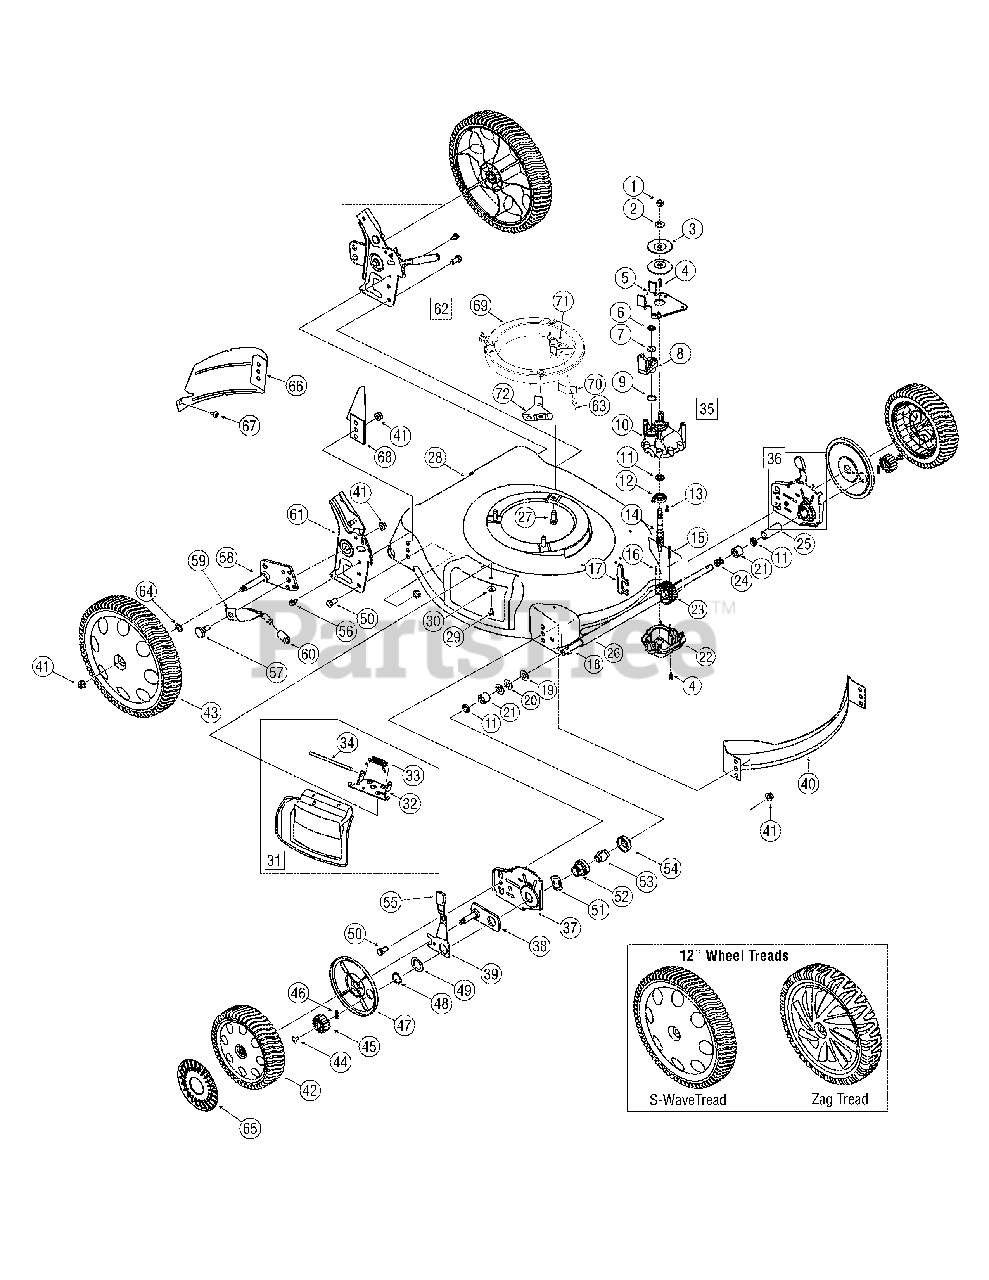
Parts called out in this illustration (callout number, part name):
1	Hex L-Nut 3/8-24
2	Cupped Washer
3	Pulley, 3.82 x .313 x .68
5	Transmission Bracket
6	Push Nut
7	Slotted Washer
10	Upper Housing
11	Oil Seal
14	Pinion Shaft
17	Shifter Fork
19	Flat Washer
21	Plastic Bushing
22	Lower Housing Ass’y
23	28 Tooth Gear
24	Com pression Spring
25	Sleeve Spacer 1.8" Lg.
26	Sleeve Spacer 9.10" Lg.
27	Hex Wash TT Sems Scr 3/8-16 x 1.875
29	Hex Wash S-Tapp Scr 1/4-20 x .50
30	Cupped Washer .265 ID x .75 OD x .062
31	Complete Mulch Plug
32	Chute Hinge
33	Torsion Spring
34	Hinge Pin
35	Transmission Ass’y Com plete
36	RH Height Adjustment Assembly
36	LH Height Adjustment Assembly
37	Height Adjuster Plate - RH
37	Height Adjuster Plate - LH
38	Height Adjuster Pivot Plate Ass'y
39	Spring Lever Front RH
39	Spring Lever Front LH
40	Front Baffle
41	Hex L-FlangeNut 3/8-16 Gr. F, Nylon
42	Wheel Ass'y 8 x 2.125 Gear Zag
42	Wheel Ass'y 8 x 2.125 Gear S-Wave
43	Wheel Ass'y 12 x 2.125 Gear Zag
43	Wheel Ass'y 12 x 2.125 Gear S-Wave
44	Pan Scr. 1/4-20 x .390
45	Spur Gear 14T RH
45	Spur Gear 14T LH
46	Pin
47	Wheel Dust Cap
48	Snap Ring for 1.0" shaft
49	Flat Washer 1.5 OD x .03
50	Hex Cap Screw 3/8-16 x .75
52	Bearing Support
53	Bearing Sleeve
54	Bearing Retainer
55	Height Adjuster Knob
56	Hex Wash Hd TT Scr. 1/4-20 x .625
57	Shoulder Screw .50 Dia. X .385
58	Pivot Arm Assembly - RH
58	Pivot Arm Assembly - LH
59	Rear Spring Lever
61	RH Handle Bracket
61	LH Handle Bracket
62	LH Handle Bracket Assembly
62	RH Handle Bracket Assembly
63	Rivet
64	Spring Washer .50 ID x 1.0 OD x .022
65	Hub Cap - Yellow
65	Hub Cap Grey Radial
66	LH Rear Baffle
67	Screw AB 1/4-14 x 0.625
68	RH Rear Baffle
69	Engine Spacer
70	Belt Keeper Bracket
71	Flat Washer
